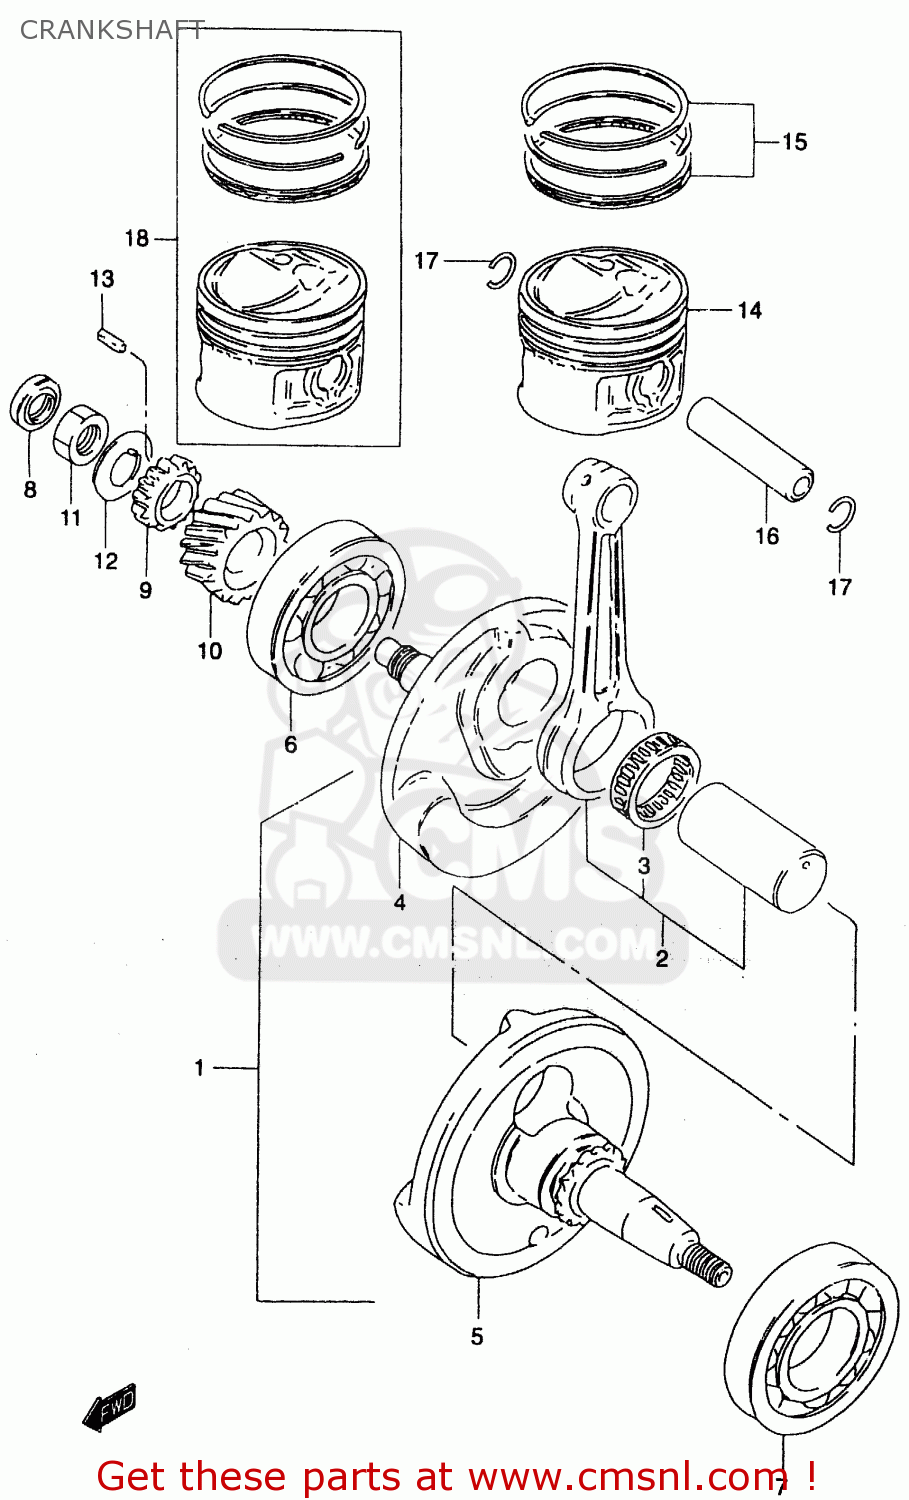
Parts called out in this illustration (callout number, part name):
1	CRANKSHAFT ASSY
2	CONNECTING ROD SET
3	BEARING(28X36X15.8)
4	CRANKSHAFT,R
5	CRANKSHAFT,L
6	BEARING(28X68X18)
7	BEARING(35X72X17)
8	SEAL,OIL(12X21X7)
9	GEAR,OIL PUMP DRIVE
10	GEAR,PRIMARY DRIVE
11	NUT
12	WASHER
13	KEY
14	PISTON
15	RING SET,PISTON
16	PIN,PISTON
17	RING,SNAP 14MM
18	PISTON SET(OS:0.5)
